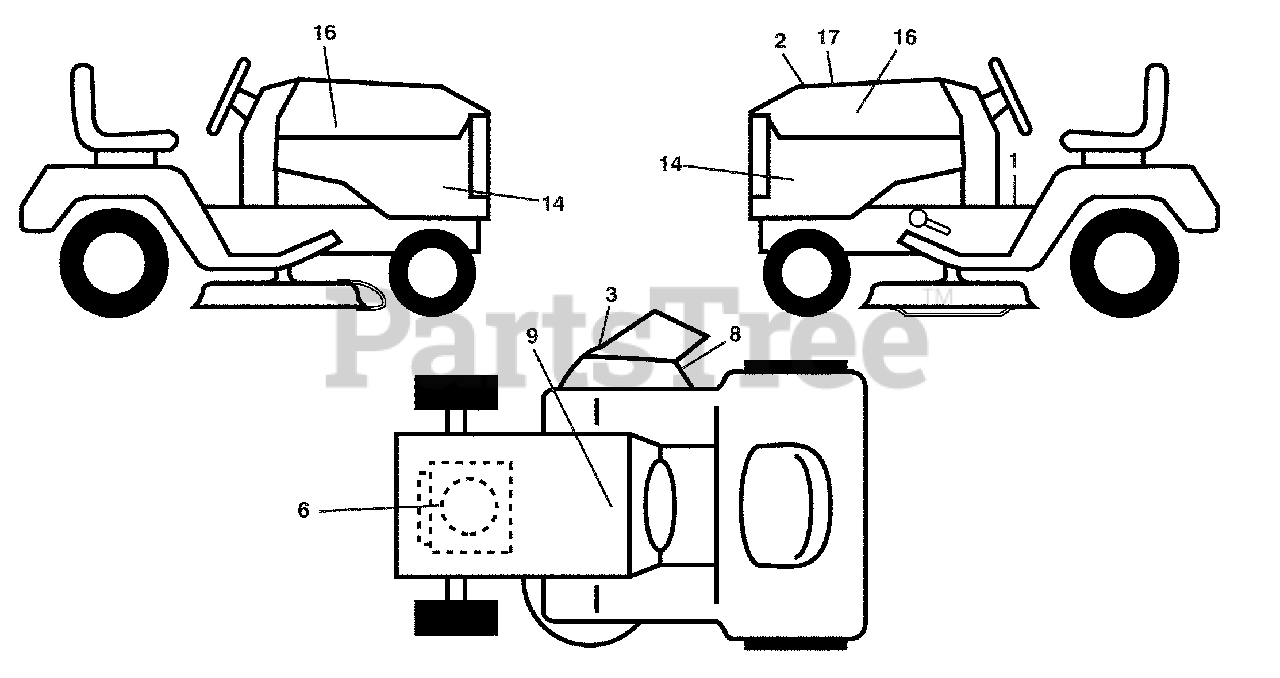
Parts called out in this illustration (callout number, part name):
1	Decal, Operator's
2	Decal, Hood Insert
3	Decal, Warning
6	Decal, Eng. HP
8	Decal, Mower Sch.
9	Decal, Battery Dnge/Poi
14	Decal, Panel Side
16	Decal, Hood Logo
17	Decal, Replacement
